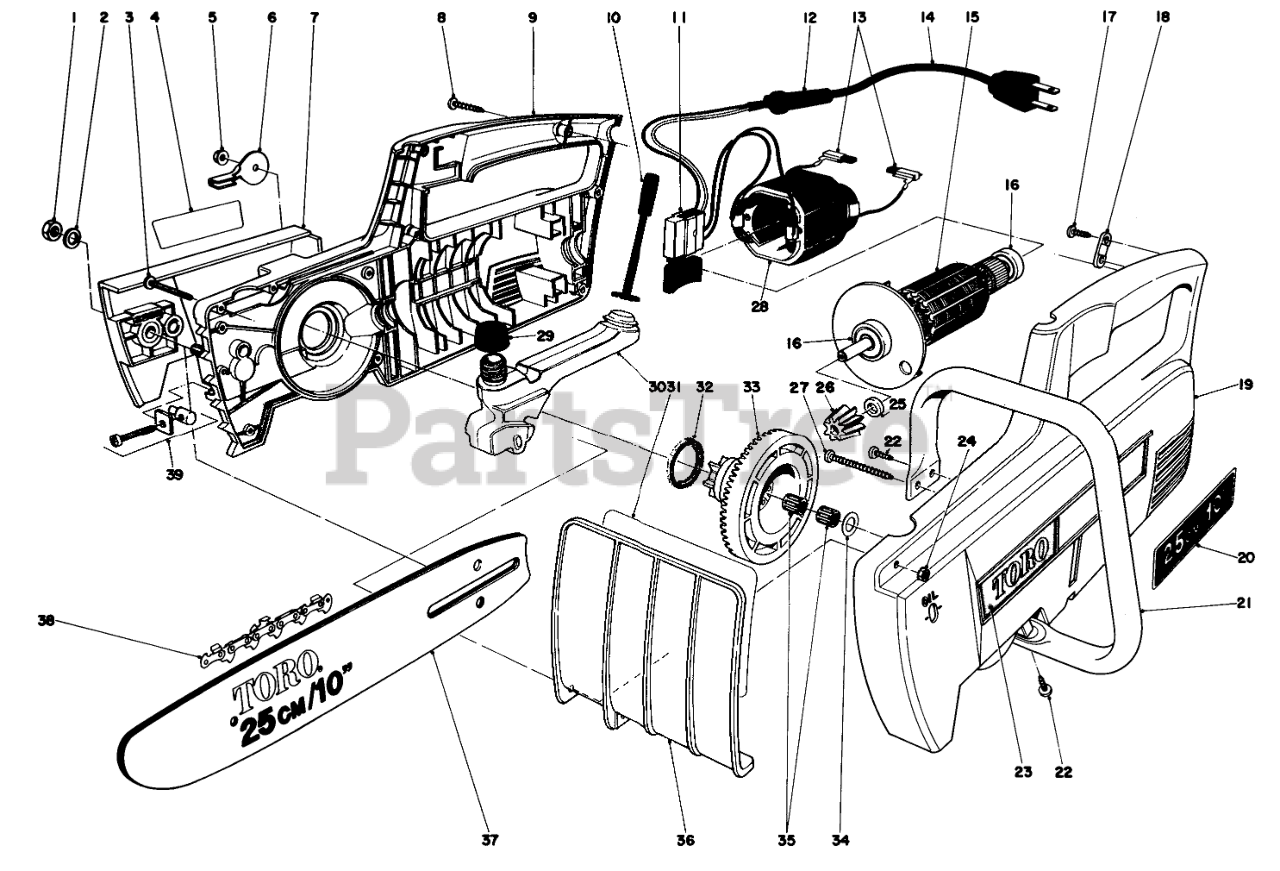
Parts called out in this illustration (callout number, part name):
2	SPRING WASHER
3	Screw
4	Decal-Toro R.H.
5	TOOTHED FLANGE NUT
6	Shaft Support Bracket
7	Sprocket Cover
8	Screw
9	Housing R.H.
10	Oil Button
11	Switch
12	Driver
13	Brush Assembly
14	Power Supply Cord
15	Armature (Including Ball Bearing)
16	Ball Bearing
17	Screw
18	Cord Clamp
19	Housing L.H.
20	Decal-Chain Saw (Model 51110)
21	Front Handle
22	SCREW-PPH
23	Decal-Toro L.H.
24	Hex Nut
25	Collar
26	Pinion
27	Screw
28	Field Assembly
29	Oil Cap
30	Oil Tank
31	Decal-Caution
32	Felt Seal
33	Sorocket Assembly
34	THRUST WASHER
35	Needle Bearing
36	HAND GUARD
37	10" CHAIN SAW BAR - C
38	10" Saw Chain
39	Adjusting Block Assembly
